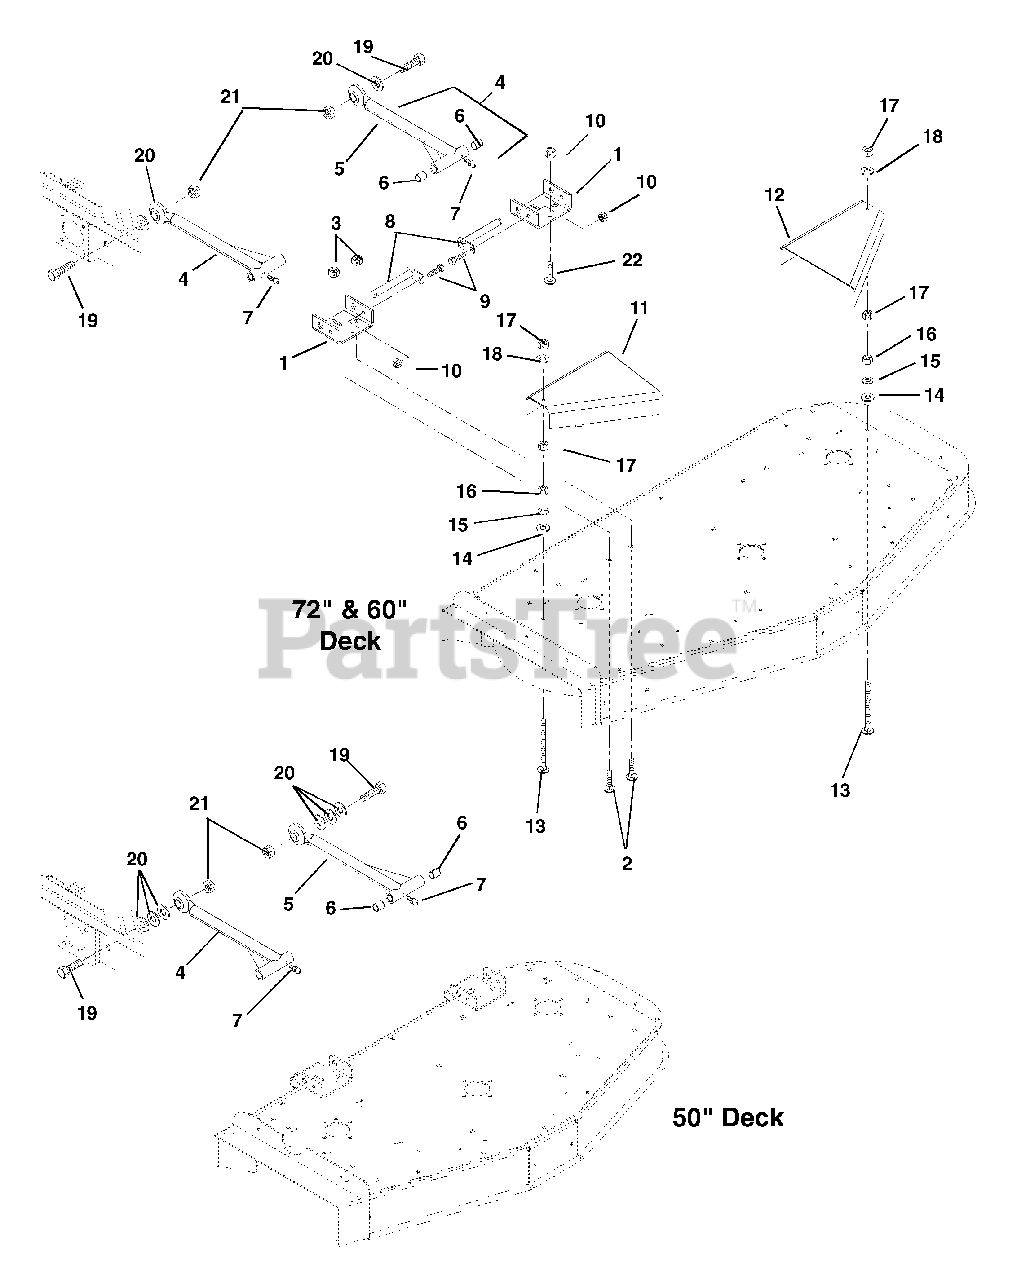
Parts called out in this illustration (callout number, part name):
1	Bracket, Mower Mounting (Rear)
2	Bolt-Round Head Square Neck .50 - 13 x 1.00 Grade 2
3	Nut-Locking-Center .50 - 13
4	Assembly, Mower Mounting Arm
5	Weldment-Mower Mounting Arm
6	Bearing .75 x .875 x 1.00
7	Fitting-Lube .25 - 28 x .256
8	Weldment, Mower Mounting Pin
9	Bolt-Hex .38 - 16 x .75 Grade 5
10	Nut-Locking-Center .38 - 16
11	Guard, Pulley Right Hand
12	Guard, Pulley Left Hand
13	Bolt-Round Head Square Neck .31 - 18 x 3.50
14	Washer-Flat-Steel .344 x .688 x .065
15	Washer-Locking .31 x .078
16	Nut-Hex .31 - 18
17	Nut-Locking-Center .31 - 18
18	Washer-Flat-Steel .438 x 1.00 x.083
19	Bolt-Hex .875 - 9 x 2.75 Grade 5
20	Washer-Flat-Steel .875 x 1.500 x .1196
21	Nut-Locking-Center .875 - 9
22	Bolt-Round Head Square Neck .38-16 x 1.00 Grade 5
